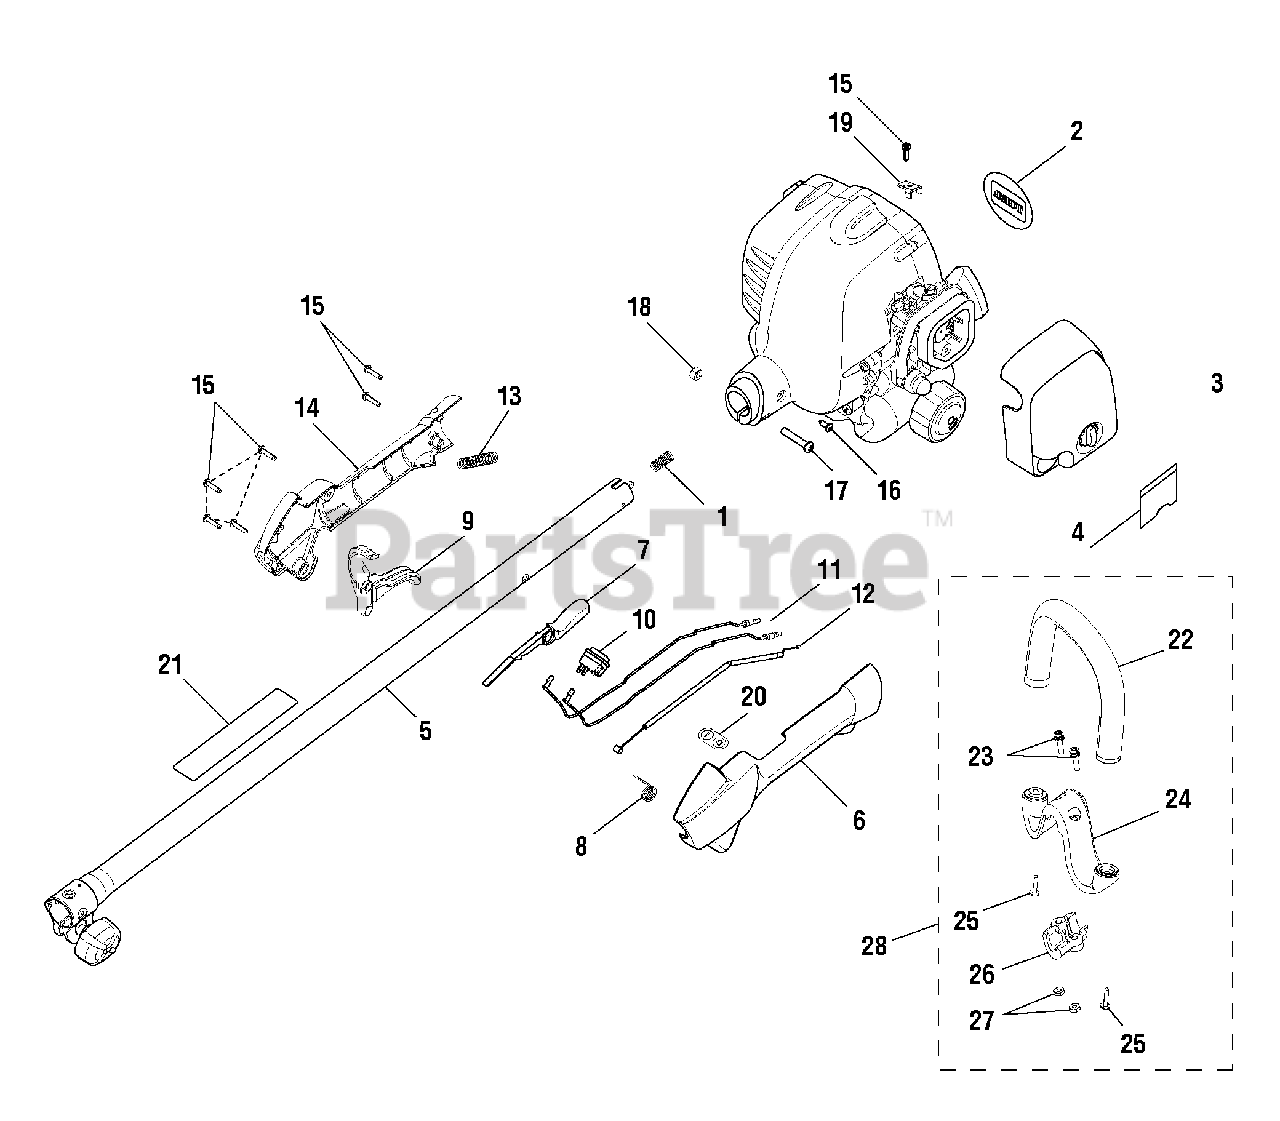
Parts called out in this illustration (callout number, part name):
1	COMPRESSION SPRING
2	LOGO PLATE
3	UPPER START LABEL
4	LOWER START LABEL
5	UPPER SHAFT ASSEMBLY
6	REAR HANDLE SUPPORT
7	LOCK-OFF BUTTON
8	TRIGGER SPRING
10	SWITCH WITH DUST SHIELD
12	CABLE, THROTTLE
13	CORRUGATED TUBE
14	REAR HANDLE COVER
15	SCREW (M4 X 16 mm)
16	SCREW (#10-14 X 1/2 in. TRI-LOBULAR)
17	SCREW (M6 X 1-30 mm)
18	HEX NUT
19	THROTTLE CABLE CLAMP
20	ON/OFF LABEL
21	WARNING LABEL
22	ASSIST HANDLE W/GRIP
23	SCREW (#12-24 X 1 in. SEMS)
24	M CLAMP
25	SLOTTED TORX SCREW
27	HEX NUT (12-24)
28	ASSIST HANDLE ASSEMBLY
